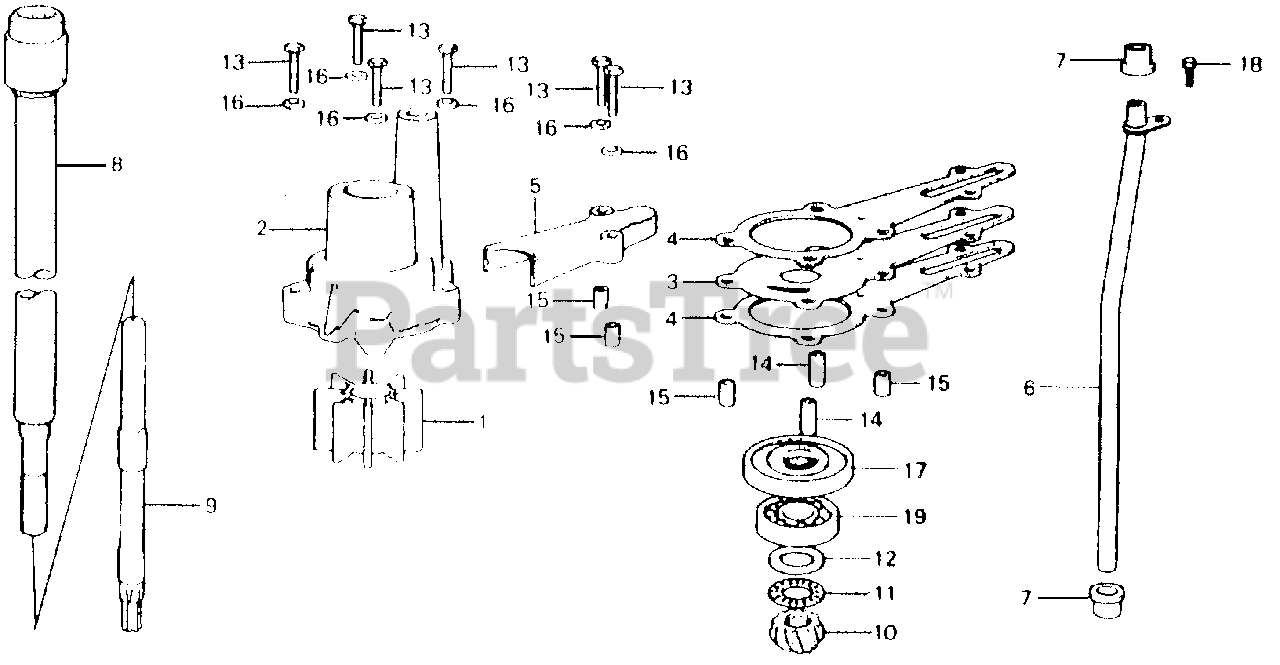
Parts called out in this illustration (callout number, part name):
1	IMPELLER, PUMP
2	HOUSING, IMPELLER
3	COVER, IMPELLER
4	GASKET, IMPELLER
5	HOLDER, IMPELLER COVER
6	TUBE, WATER (S) (NOT AVAILABLE)
7	RING, SEAL
8	SHAFT, VERTICAL (S)
9	SHAFT, PINION
10	PINION, BEVEL
11	BEARING, THRUST (15MM)
12	WASHER A, THRUST BEARING (2.00MM)
12	WASHER B, THRUST BEARING (2.05MM)
12	WASHER C, THRUST BEARING (2.10MM)
13	BOLT, HEX. (6X28)
14	COLLAR A, DISTANCE (NOT AVAILABLE)
15	COLLAR B, DISTANCE
16	WASHER, PLAIN (6MM)
17	SEAL, WATER (15MM) (NOK)
18	BOLT, HEX. (6X12)
19	BEARING, RADIAL BALL (6302)
